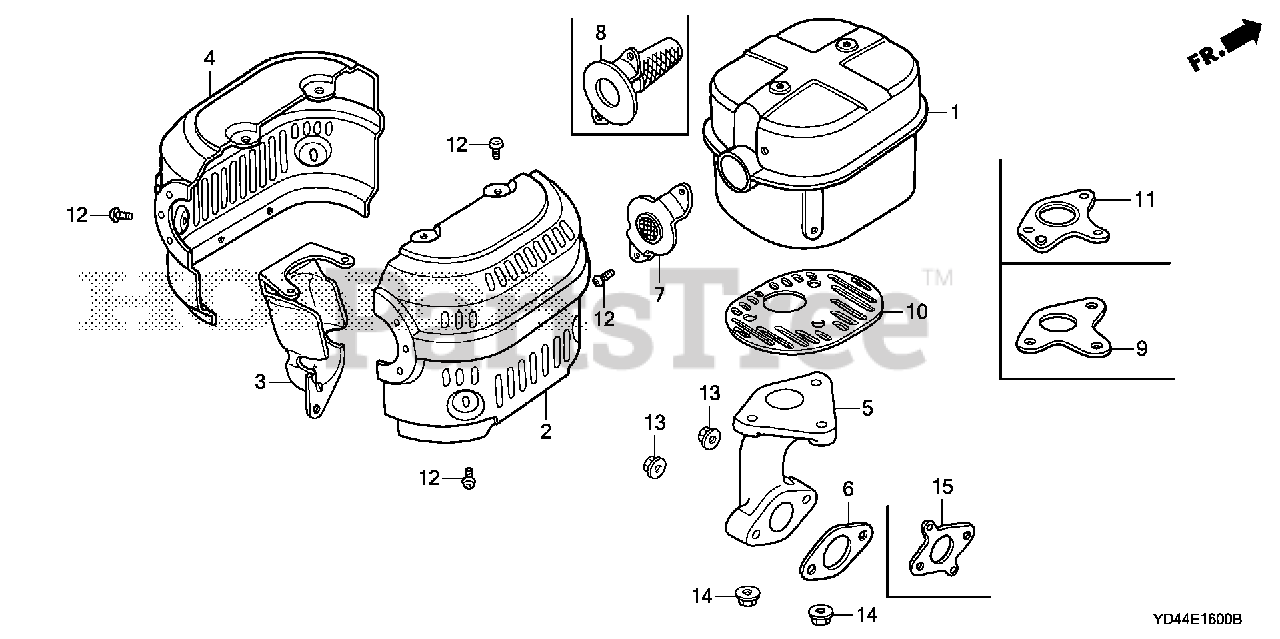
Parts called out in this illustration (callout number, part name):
1	MUFFLER
2	PROTECTOR, R. MUFFLER (ALUMINIZED)
4	PROTECTOR, L. MUFFLER (ALUMINIZED)
5	PIPE, EX.
6	GASKET, EX. PIPE Use up to Engine SN 2949254.
6	GASKET, EX. PIPE (WACKER)
7	FLANGE, BAFFLE
8	ARRESTER, SPARK
9	GASKET, MUFFLER
9	GASKET, MUFFLER (NIPPON LEAKLESS)
11	GASKET, MUFFLER (ARRESTER)
12	SCREW, TAPPING (5X8)
13	NUT, FLANGE (8MM)
14	NUT, FLANGE (8MM)
